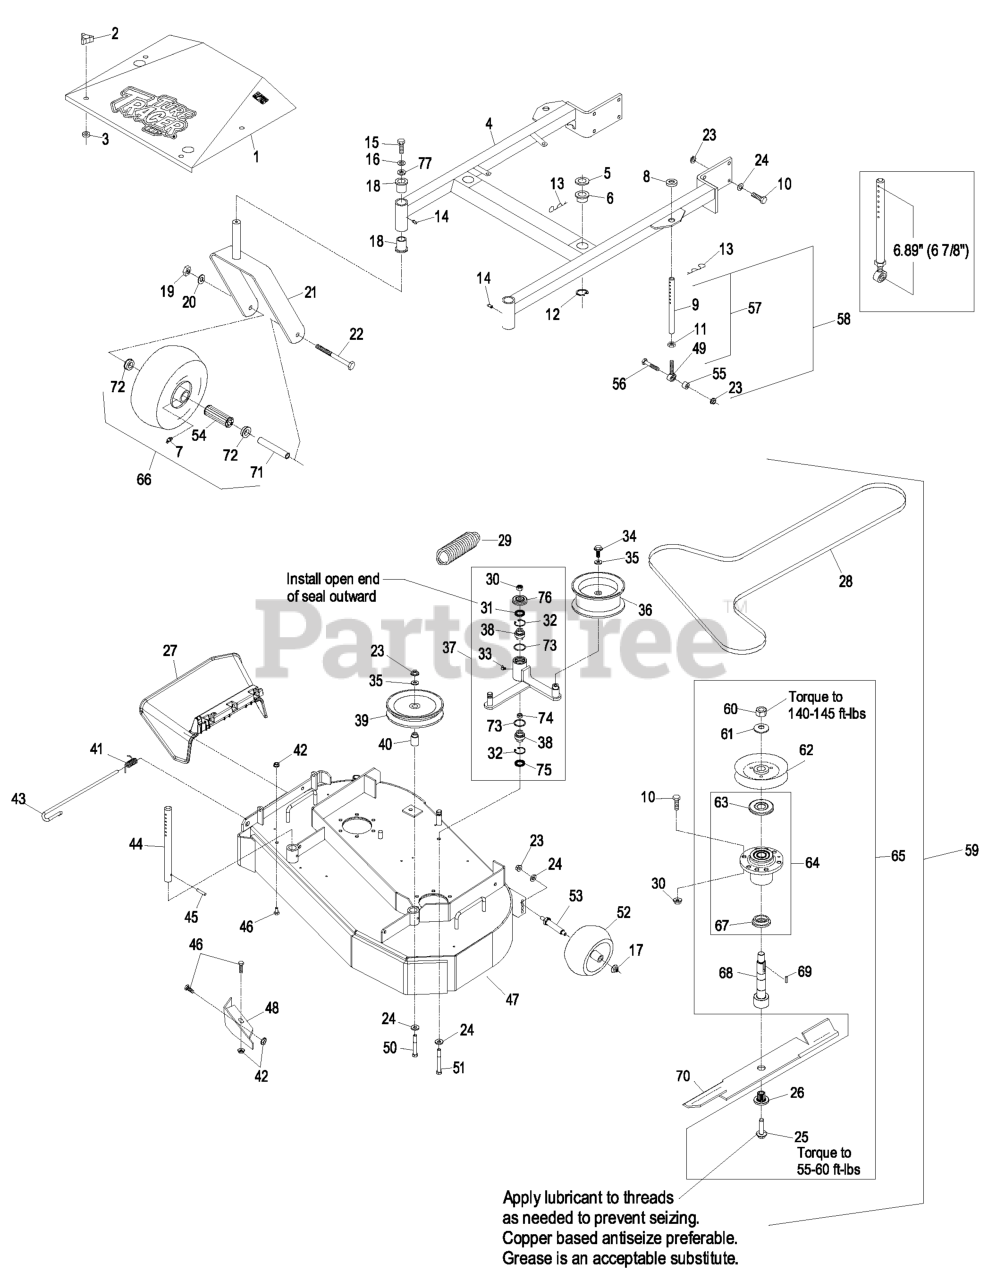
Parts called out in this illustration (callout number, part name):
1	ASM,SHIELD W/DECALS 36 TT
2	KNOB-3 PRONG
4	DECK SUPPORT W/BSHGS 36"
5	SPACER-DECK SUPPORT
6	BUSHING-DECK
7	FITTING-GREASE
9	LINK,SUPPORT
10	SCREW-HH
11	NUT-HJ
12	RING-RETAINING
13	PIN,HAIR COTTER
14	FITTING-GREASE
15	SCREW-HH
16	WASHER-LOCK
17	Nut-Nyloc 3/8-16 Flg
18	BEARING-FLANGED
19	NUT-HH
20	WASHER-LOCK
22	SCREW-HH
23	NUT-HHF, WHIZ
24	WASHER-BELLEVILLE
25	SCREW,SEMS 1/2-20 X 2.19
26	BUSHING,SPLINED
27	CHUTE DEFLECTOR XRK M056
28	BELT,DECK DRIVE
30	NUT-LOCK, NI
31	SEAL-LIP, SINGLE
32	RING-SNAP
33	FITTING-GREASE, 90 DEG
34	SCREW-HHF
35	WASHER-FLAT
37	KIT, DECK IDLER TTHP 36"(
38	BEARING-SPHERICAL
39	PULLEY-IDLER
40	BUSHING-IDLER
41	SPRING, TORSION
43	PIN-CHUTE
44	ROD,DECK SUPPORT
46	SCREW-HH
47	ASM,DECK W/DECALS TTHP/MH
49	BALLJOINT
50	SCREW-HH
51	SCREW-HH
52	ROLLER-SCALP, ANTI
54	BEARING
56	SCREW-HH
58	KIT,SUPPORT LINK W/PIN
59	Asm, Deck Complete
62	SHEAVE,W/HUB 5.72
63	GUARD-BEARING, TOP
64	KIT, CUTTER HOUSING
65	ASM, CUTTER HSG
66	KIT, SP CASTER WHEEL REPL
67	SPACER-GUARD, BOTTOM
68	KIT, SPLINED SPINDLE 103-
69	KEY-RECTANGLE
72	BUSHING
75	SEAL-LIP, DOUBLE
76	GUARD-TOP
